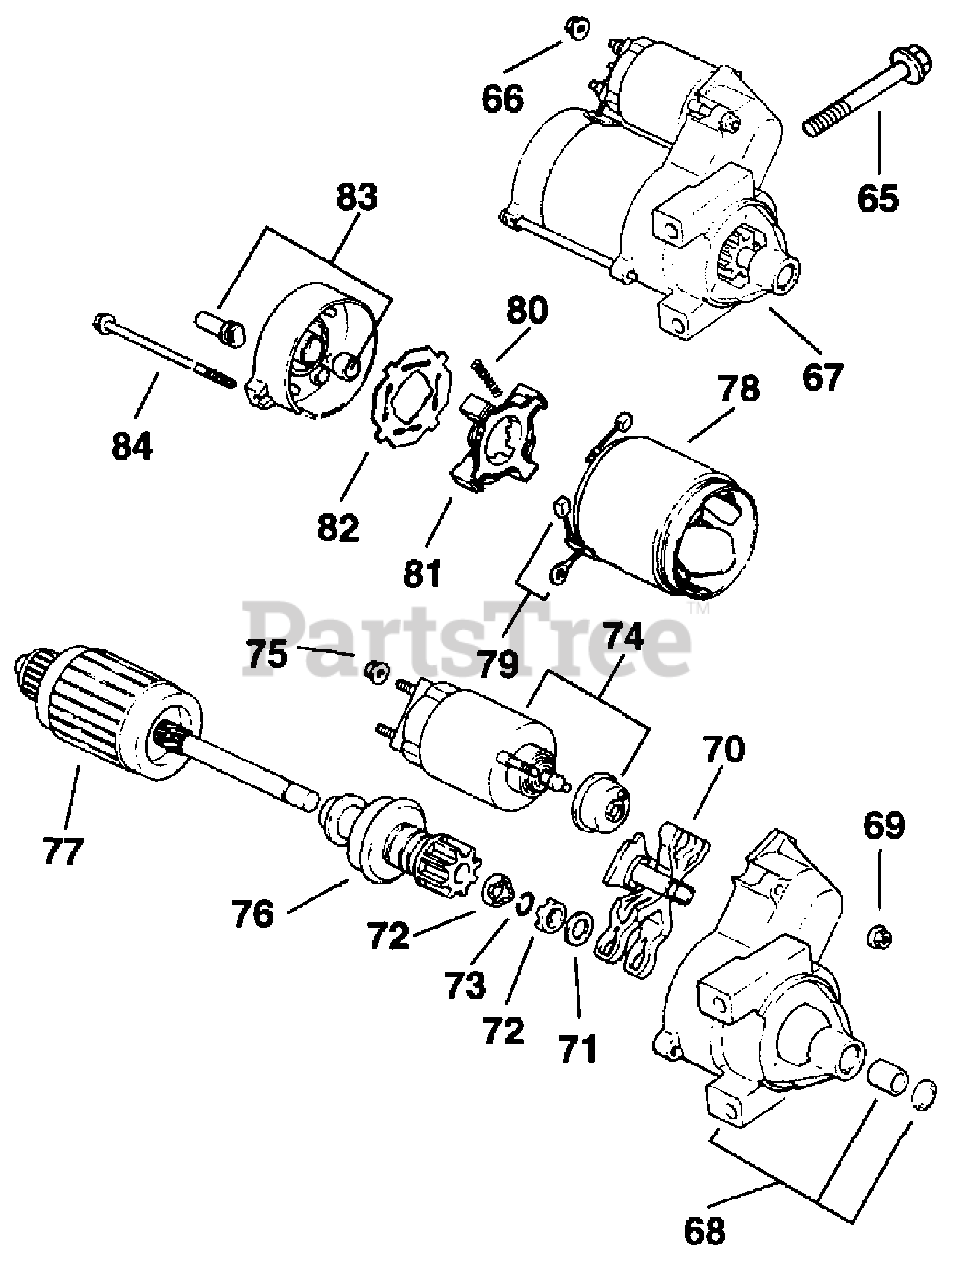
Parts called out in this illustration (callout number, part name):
65	Screw, hex. flange M8x1.25x80
66	NUT - USE M-841080
68	DRIVE END CAP
69	NUT
70	LEVER, DRIVE
71	KIT - USE 24 755 84
72	KIT - USE 24 755 84
73	KIT - USE 24 755 84
74	SOLENOID
75	NUT
76	DRIVE PINION
77	ARMATURE - DISCONTINUED
78	FRAME W/BRUSHES - DISCONTINUED
79	BRUSH & SPRING KIT
80	SPRING, BRUSH
81	BRUSH HOLDER
82	INSULATOR
83	COMMUTATOR END CAP - DISCONTINUED
84	THRU BOLT
5235701-S	Lubricant, Inertia Drive Starter (0.25 oz.)
